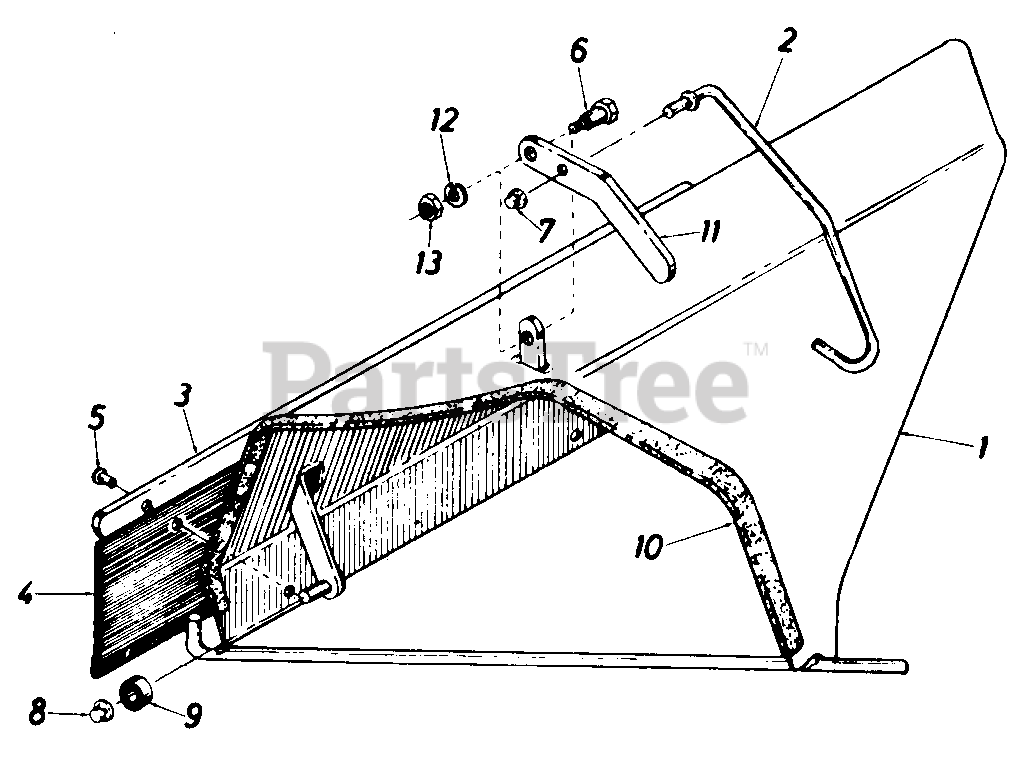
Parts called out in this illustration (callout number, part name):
1	Deflector Ass'y.
2	Hook Ass'y.
3	Retaining Strip
4	F lap
5	Rivet
6	Shld. Bolt.375" Dia. x . 171 Lg.
7	Palnut 1/4" Rod
8	Palnut 3/8" Rod
9	Roller
10	Moulding
11	Latch Arm
12	L-Wash. 1/4" I.D.*
13	Hex Nut 1/4-20 Thd.
